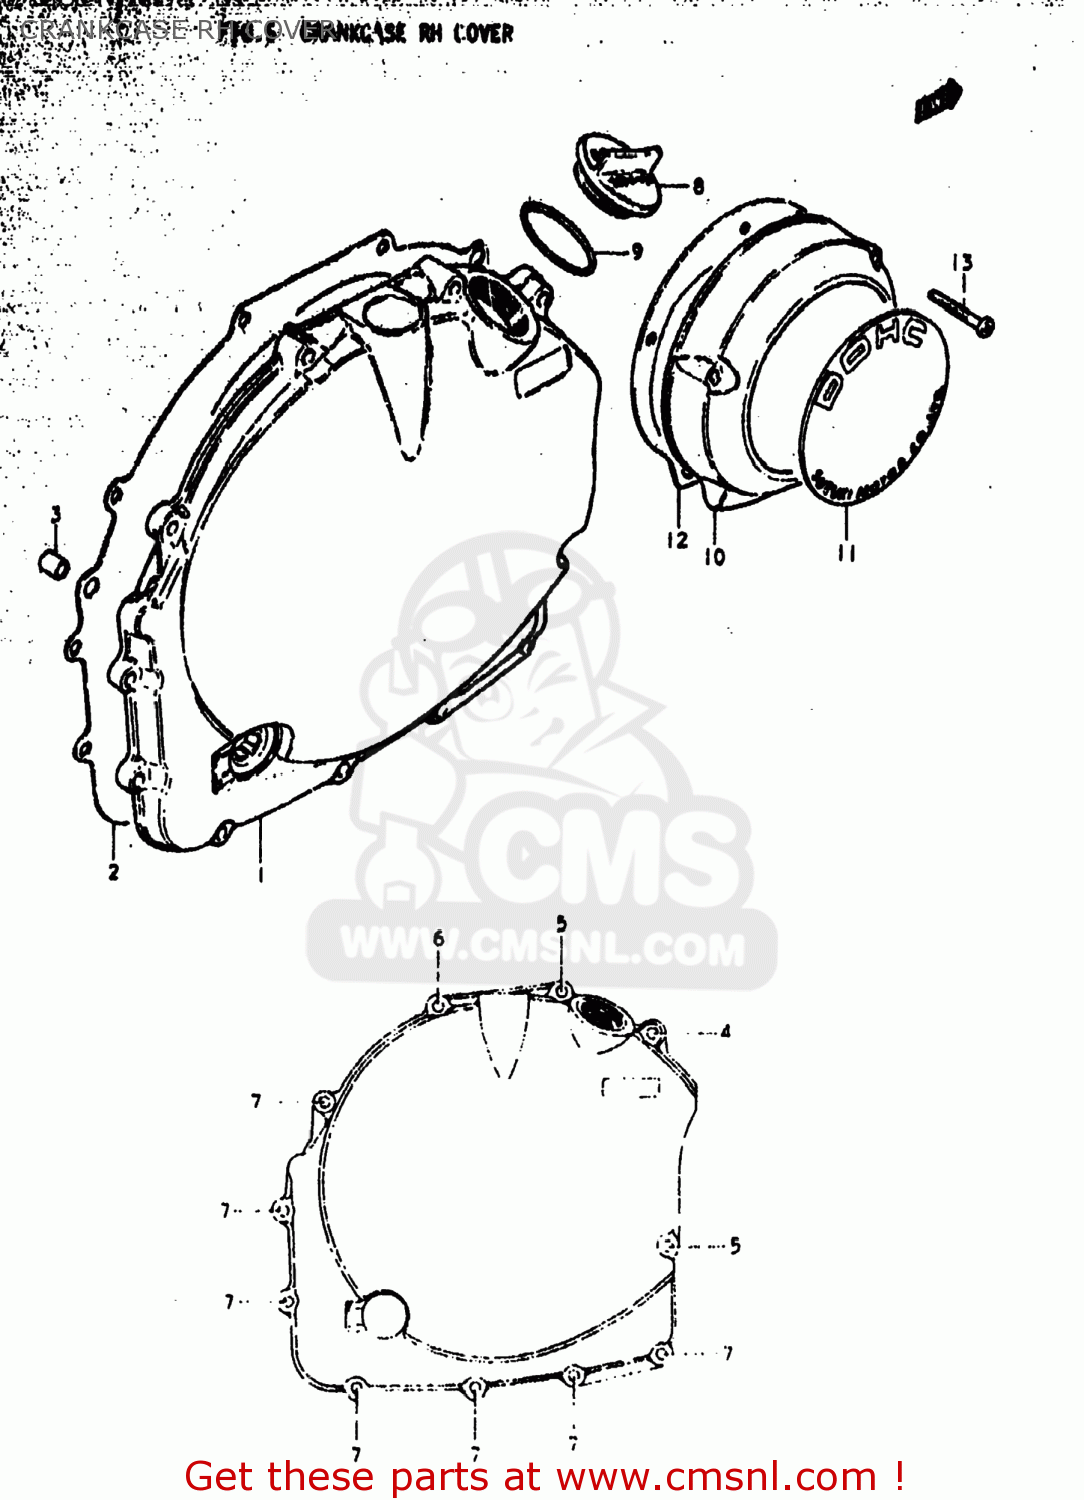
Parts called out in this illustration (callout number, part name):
1	COVER,CLUTCH
2	GASKET,CLUTCH COVER (MCA)
3	PIN
4	SCREW (6X35)
5	SCREW (6X35)
6	SCREW
7	SCREW
8	CAP
9	O RING(D:2.2,ID:32)
10	COVER,CONTACT BREAKER
11	EMBLEM
12	GASKET,CONTACT BREAKER COVER (NAS)
13	SCREW
